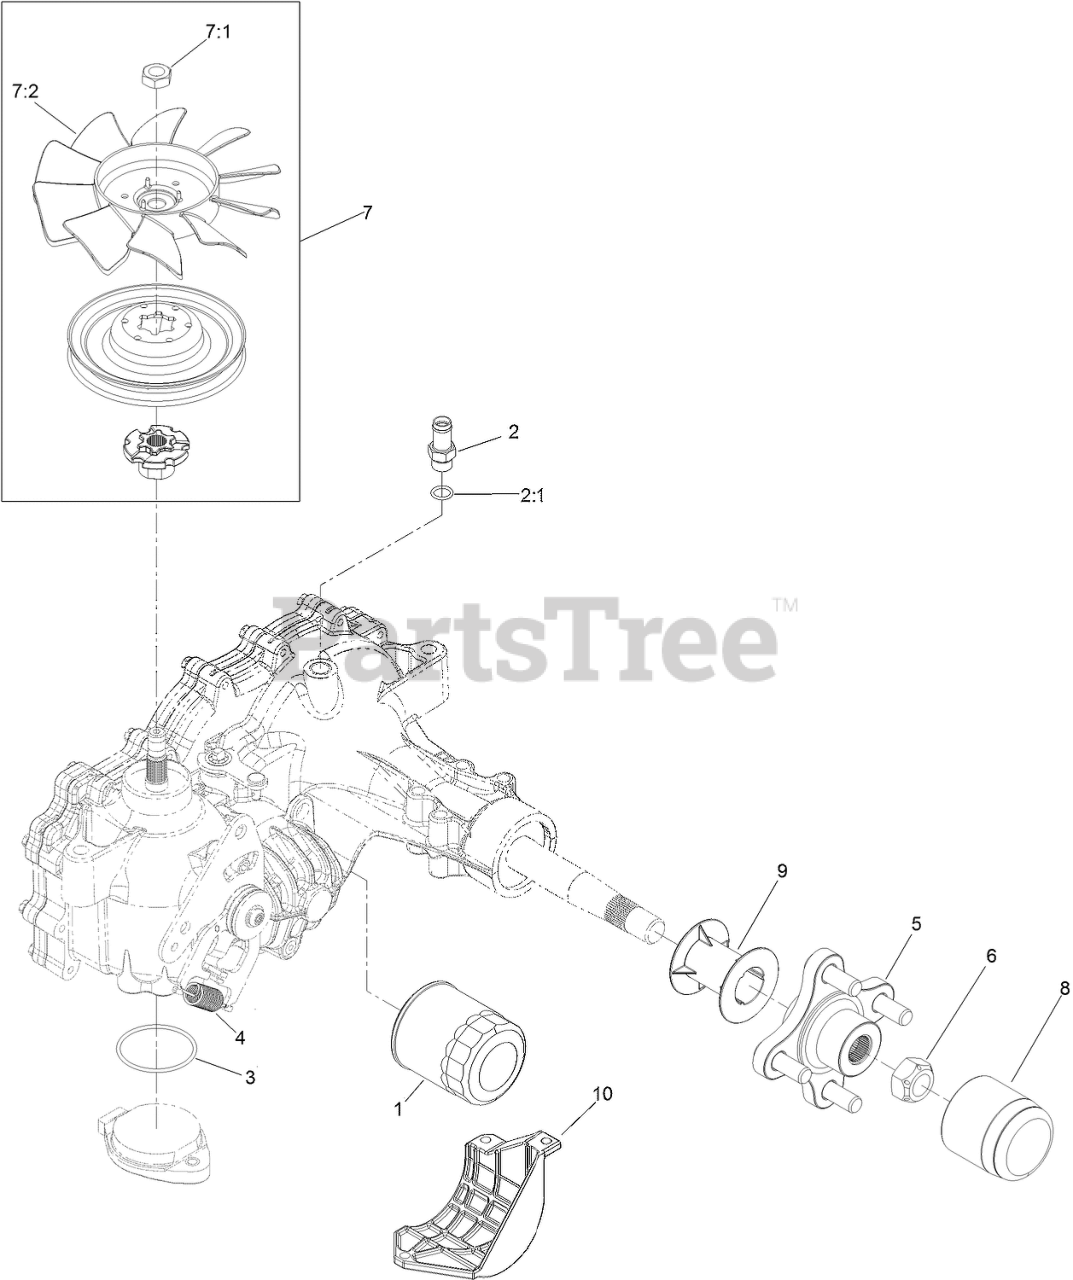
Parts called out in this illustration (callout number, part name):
1	ELEMENT-OIL FILTER, HYD
2	ADAPTER-STRAIGHT
2:1	O-RING
3	O RING-SEAL
4	SPRING-EXTENSION
5	HUB-OFFSET
6	NUT-HUB
7	FAN AND PULLEY KIT
7:1	NUT-HJ
8	CAP-AXLE, LONG
9	TUBE-AXLE
10	GUARD-FILTER, LH
99	BRAKE SHAFT SEAL KIT
